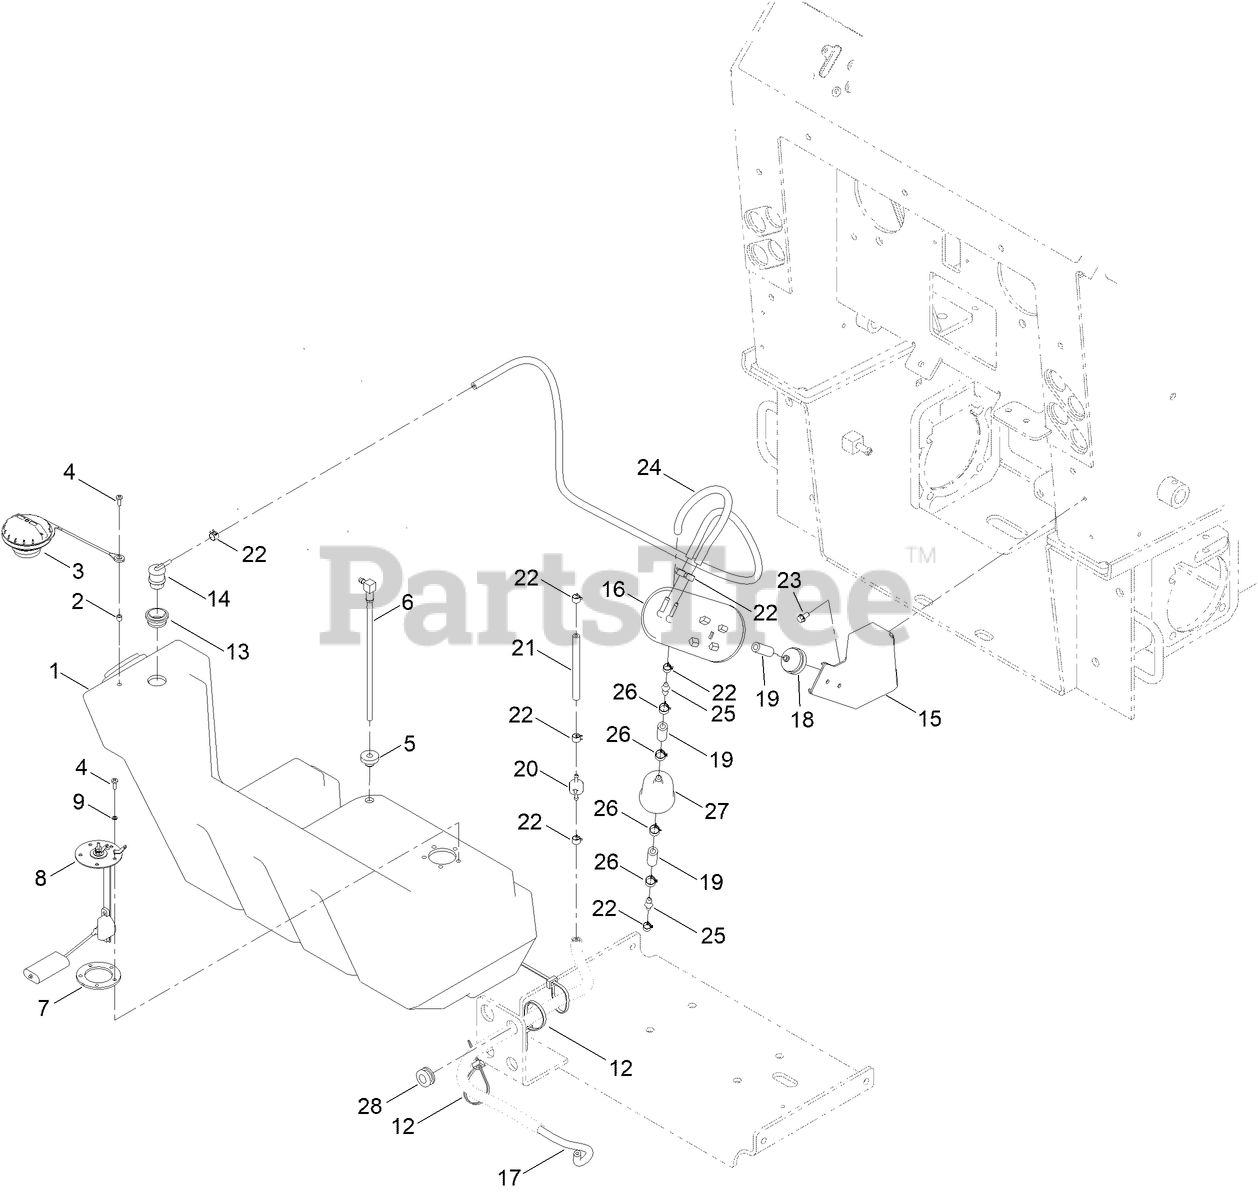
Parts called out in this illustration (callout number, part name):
1	TANK-FUEL
2	SPACER
3	CAP-FUEL
4	SCREW-PPH
5	BUSHING
6	PIPE-STAND
7	GASKET-SENDER, FUEL
8	SENDER-FUEL
9	WASHER-LOCK
12	TIE-CABLE
13	GROMMET
14	VALVE-ROLLOVER
15	HOLDER-CANISTER
16	CANISTER-CARBON
17	HOSE-FUEL
18	FILTER-FUEL, INLINE
19	HOSE-FUEL
20	VALVE-CHECK, VACUUM
21	HOSE-FUEL
22	CLAMP-HOSE
23	SCREW-HWH
24	HOSE-FUEL
25	FITTING-STRAIGHT
26	CLAMP-HOSE
27	FILTER-FUEL
28	GROMMET
